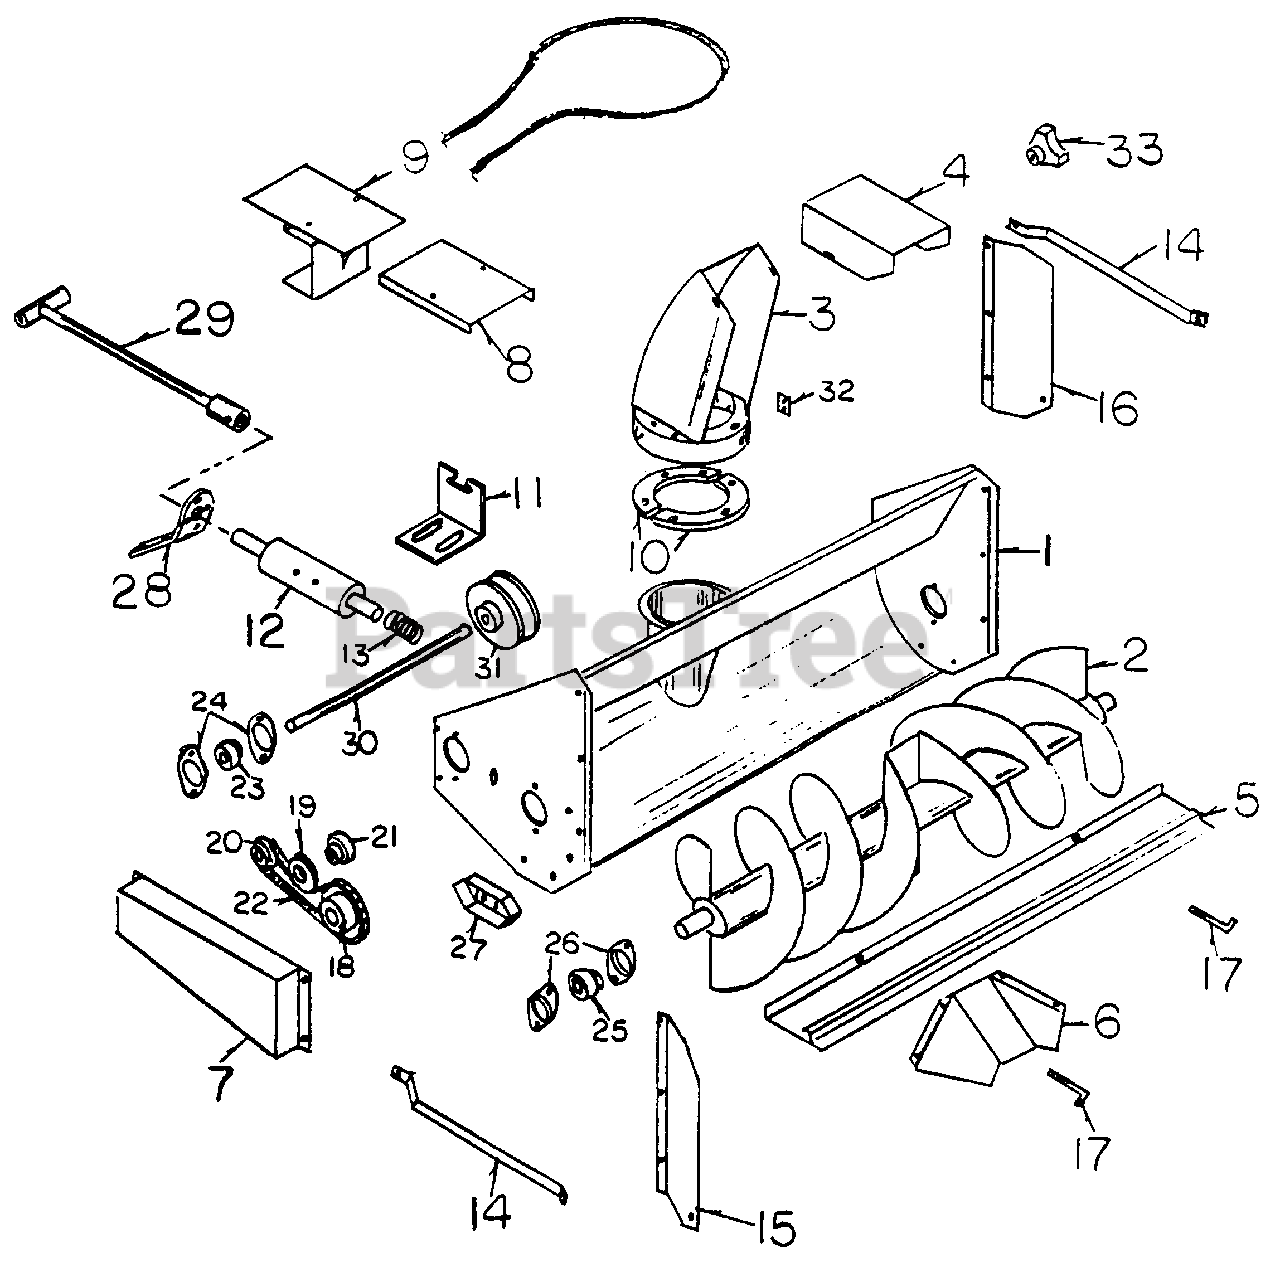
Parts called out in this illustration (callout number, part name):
1	Snow Blower Housing
2	Augser
3	Chute
4	Snow Deflector
7	Chain Guard
8	Belt Guard
9	Belt Guard
11	Cable Retainer
12	Cable Pulley
13	Spring
14	Extender Brace
15	R. H. Extender
16	L. H. Extender
17	Blade Bolt
18	Auger Sprocket
19	Idler Sprocket
20	Drive Sprocket
21	Idler Sporcket Bushing
24	3/4" Bearing Flange
25	1" Bearing
26	1" Bearing Flange
28	Cable Pulley Support
29	Handle
30	Shaft
32	Cable Clamp
